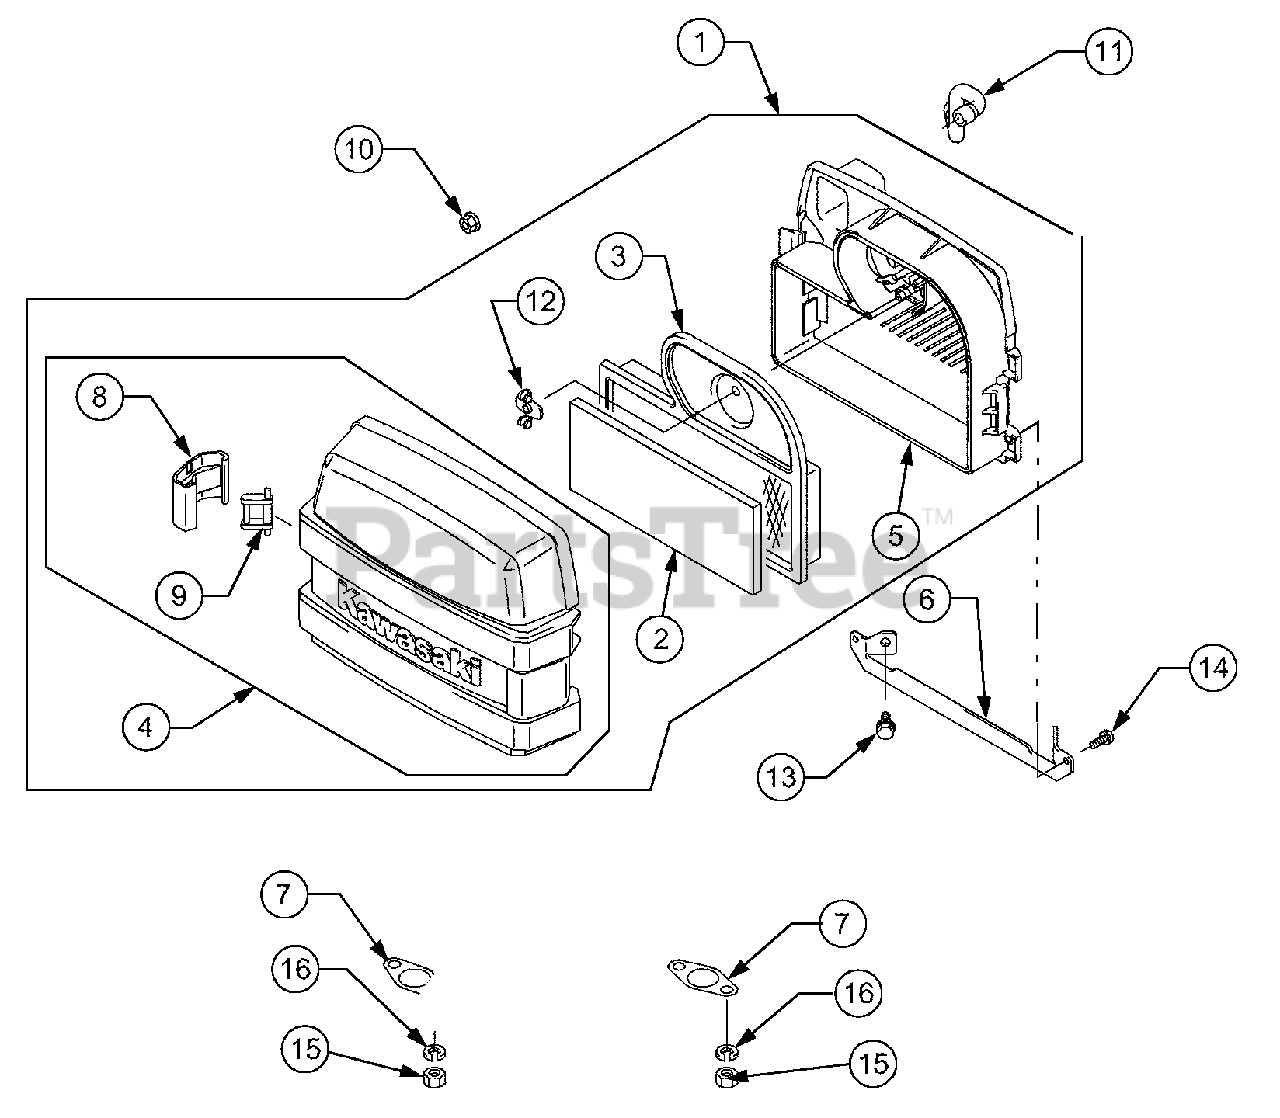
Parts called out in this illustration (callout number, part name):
1	Filter Assy, Air
2	Element, Air Filter
3	Element, Air Filter
4	Case Assy, Air Filter
5	Case Assy, Air Filter
7	Gasket, Muffler
8	Hook, Air Filter
9	Joint
10	Nut
13	Bolt, Flanged
14	Screw, Pan-ws+-
15	Nut, Hex - Small
16	Washer, Spring
